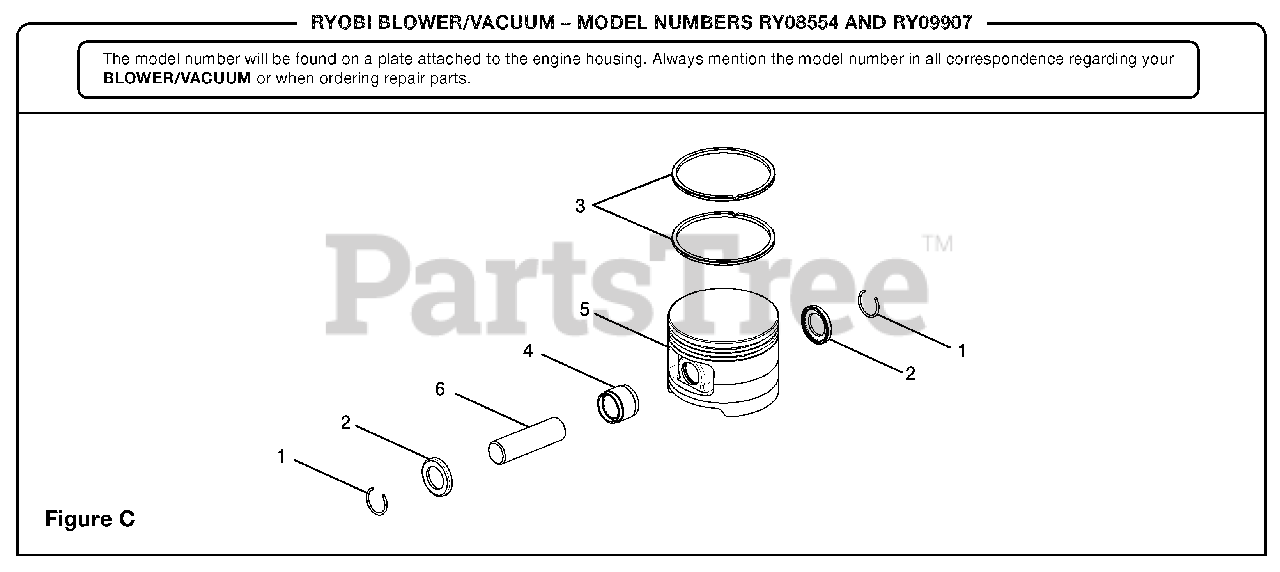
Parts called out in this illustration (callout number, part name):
1	Circlip Pin
2	washer
3	Histon riino
4	Needle Bearing
6	Piston Pin
